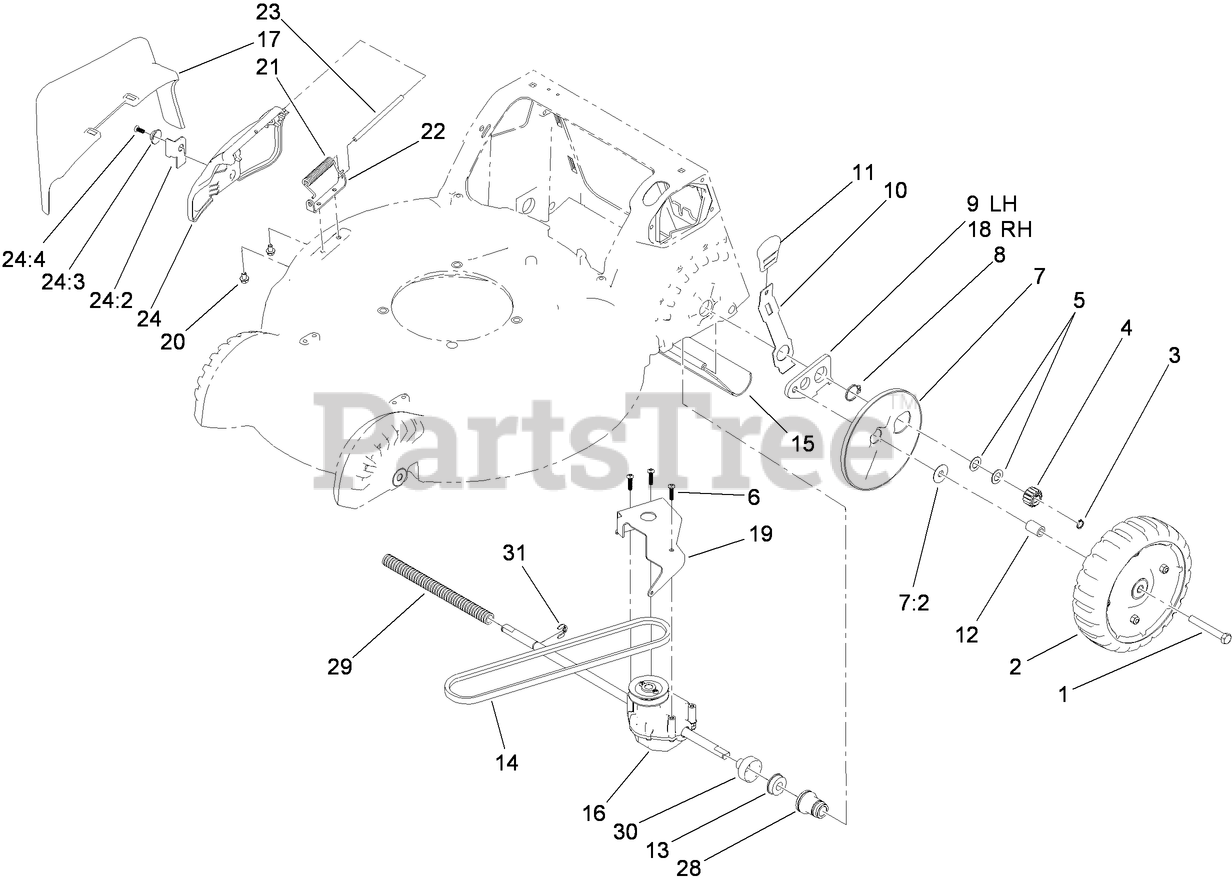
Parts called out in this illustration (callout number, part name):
1	SCREW-HH
2	8 INCH WHEEL ASM
3	RING-RETAINING
4	GEAR-PINION, 15T
5	WASHER-PLAIN
6	SCREW-PLASTITE
7	WHEEL COVER ASM
7:2	WASHER-STEPPED
8	RING-RETAINING
9	ARM-REAR PIVOT, LH
10	ARM-SPRING, REAR
11	Knob-Lever, HOC
12	SPACER
13	BEARING-BALL
14	V-BELT
15	SHIELD-TRAILING
16	TRANSMISSION
17	CHUTE-DISCHARGE, SIDE
18	ARM-REAR PIVOT, RH
19	BRACKET-TRANSMISSION
20	SCREW-HWH
21	SPRING-TORSION
22	BRACKET-COVER
23	ROD-COVER
24	DISCHARGE DOOR ASM
24:2	LATCH-DOOR
24:3	CAP-DOOR
24:4	SCREW-PLASTITE
28	RETAINER-BEARING
29	CONDUIT-CONVOLUTED, SPLIT
30	CAP-BEARING
31	RING-CLIP, LOCKING
